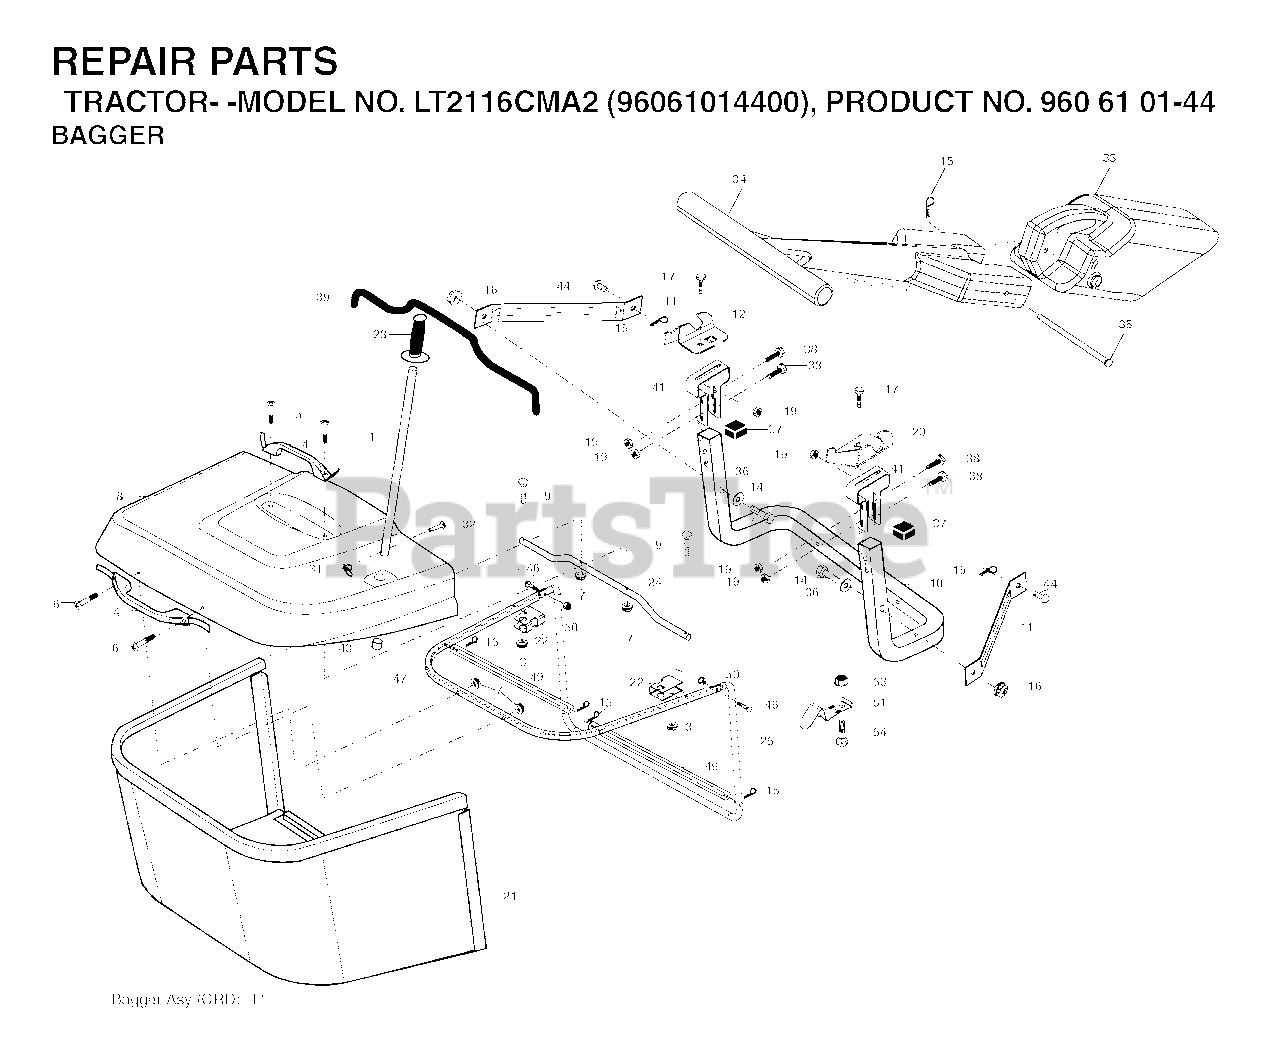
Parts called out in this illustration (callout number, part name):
1	TUBE HANDLE
3	NUT T
5	SCREW.PAN.HEAD
11	BRACKET
14	BOLT-HEX EAK
15	RETAINER-SPRNG RB
16	NUT LOCK FLG 3/8-16 UNC
17	BOLT
19	NUT LOCK HEX FLANGE 5/16-18
20	BRKT.PIVOT.RH.CRD
22	BRACKET
24	TUBE
28	GRIP.HANDLE.BLACK
31	RETAINER CLIP
32	RIVET,DRILLED
33	PLUG
35	PIN
38	BOLT.5/16-18X2.5
41	BRKT, BAGGER
43	PLUG, TUBING END
46	BOLT.CARRIAGE.5/16-18
50	NUT.71038.31-18.HEX.NYLOCK
53	NUT
54	BOLT
